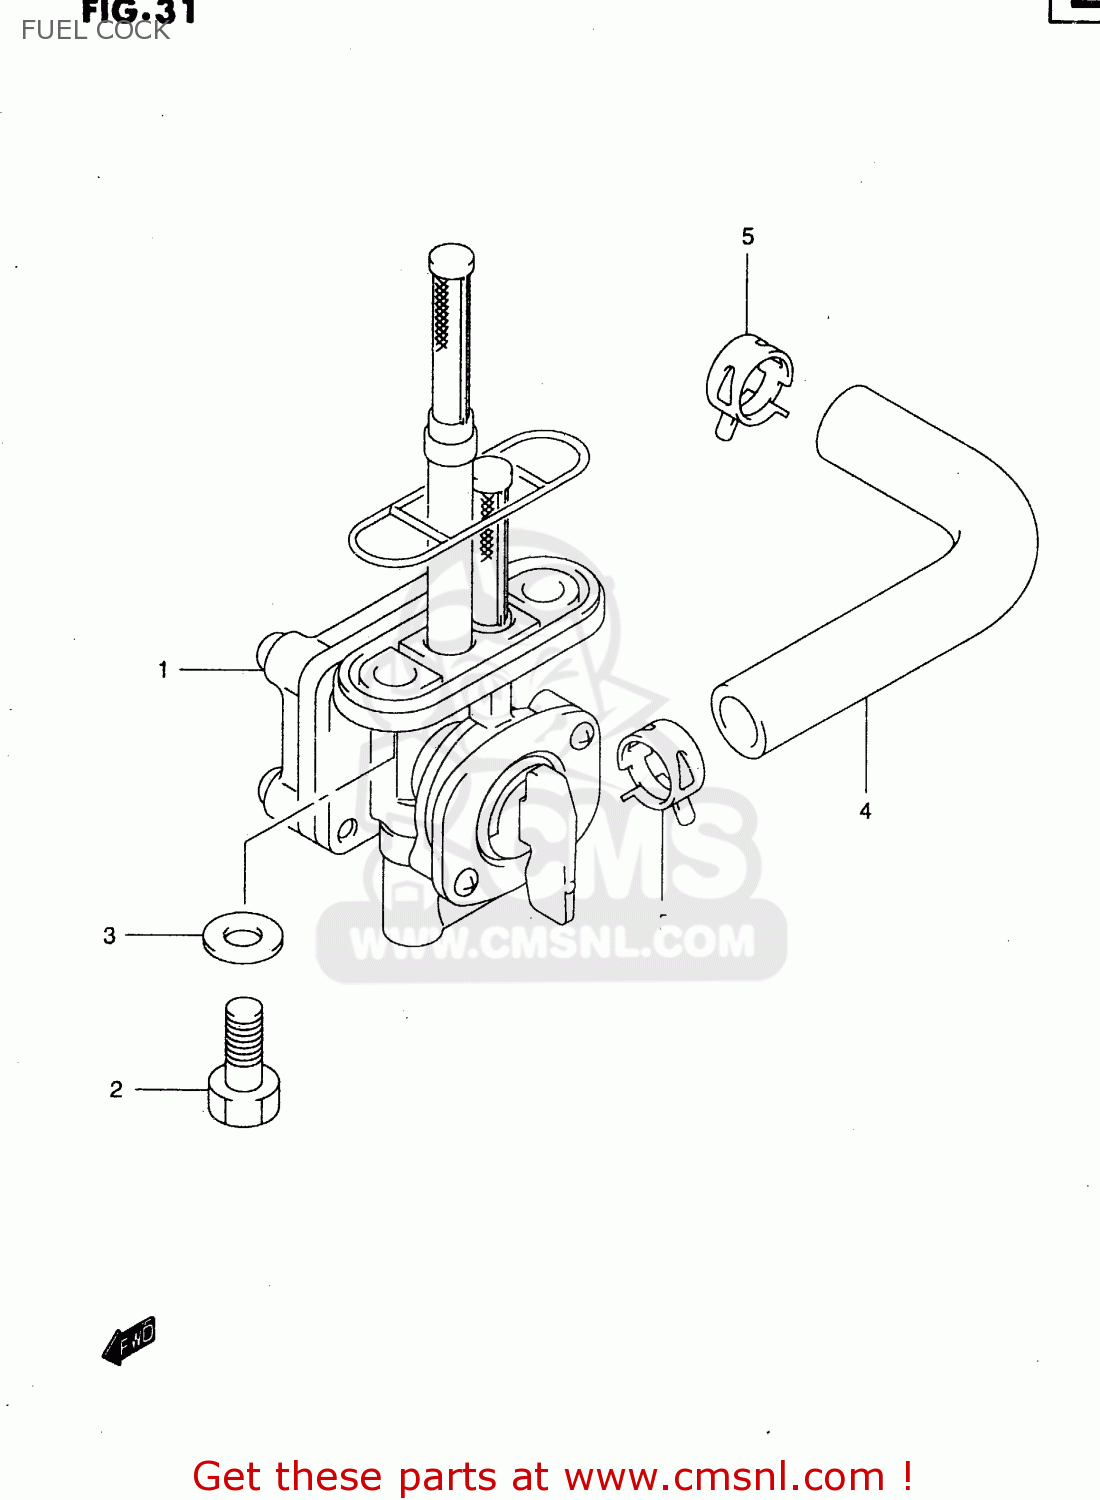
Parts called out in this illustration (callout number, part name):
1	COCK ASSY,FUEL
2	BOLT(6X20)
3	GASKET(6.4X11.5X0.8) (NAS)
4	HOSE(7X12X600)
5	CLIP
